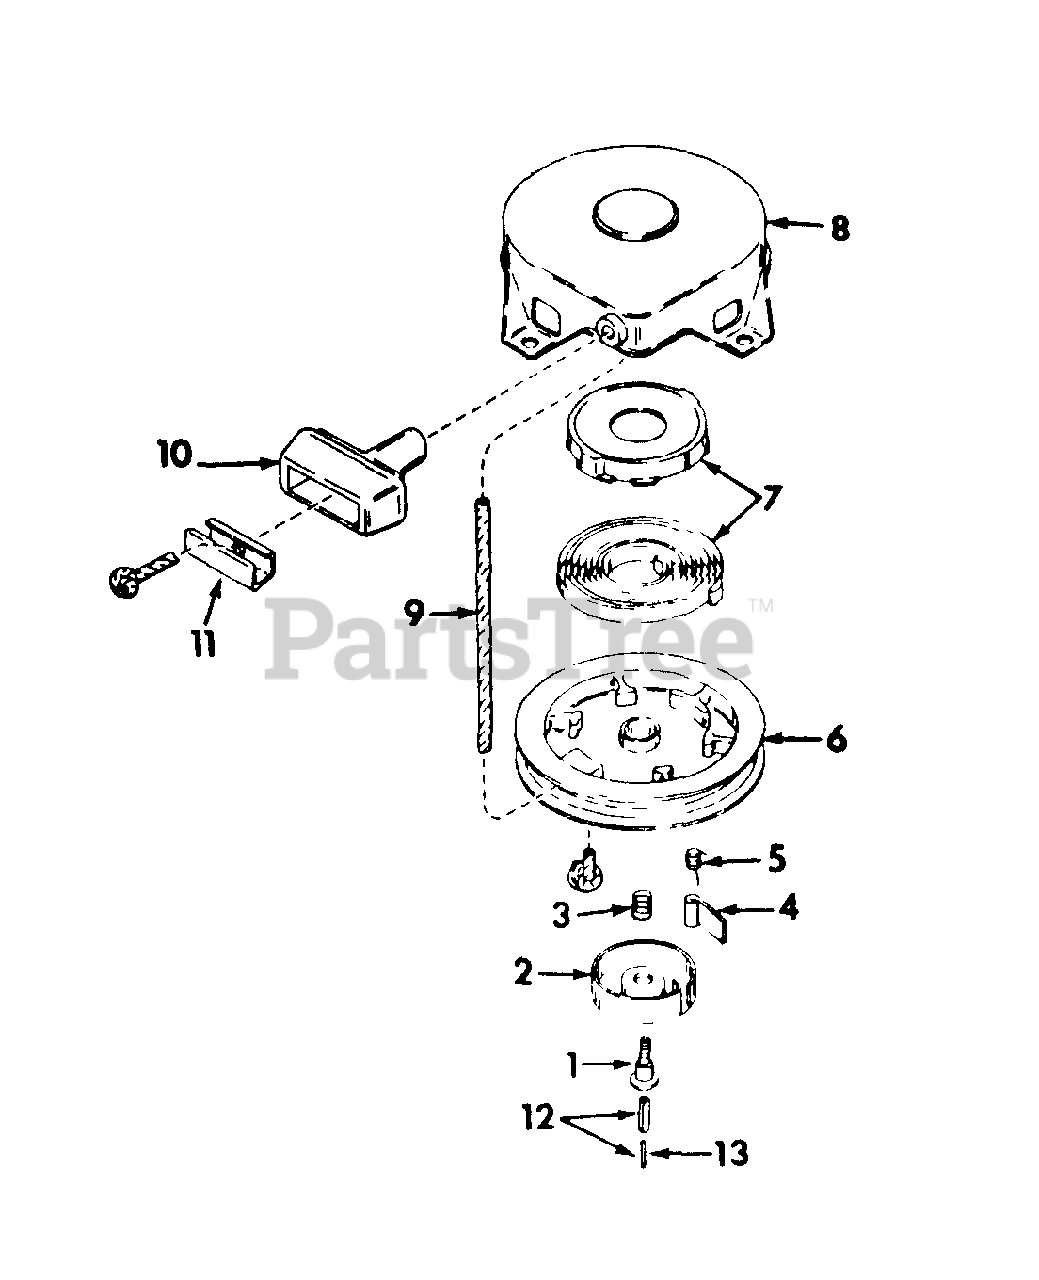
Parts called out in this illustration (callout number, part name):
1	SCREW, RETAINER
2	RETAINER, RH
3	SPRING, BRAKE
4	DOG, STARTER
5	SPRING, RH DOG
7	SPRING AND KEEPER ASSY
8	HOUSING ASSY, STARTER
9	ROPE, STARTER
10	HANDLE, STARTER
11	INSERT, STARTER HANDLE
13	PIN, 3/32 X 1 SLT SPRING
